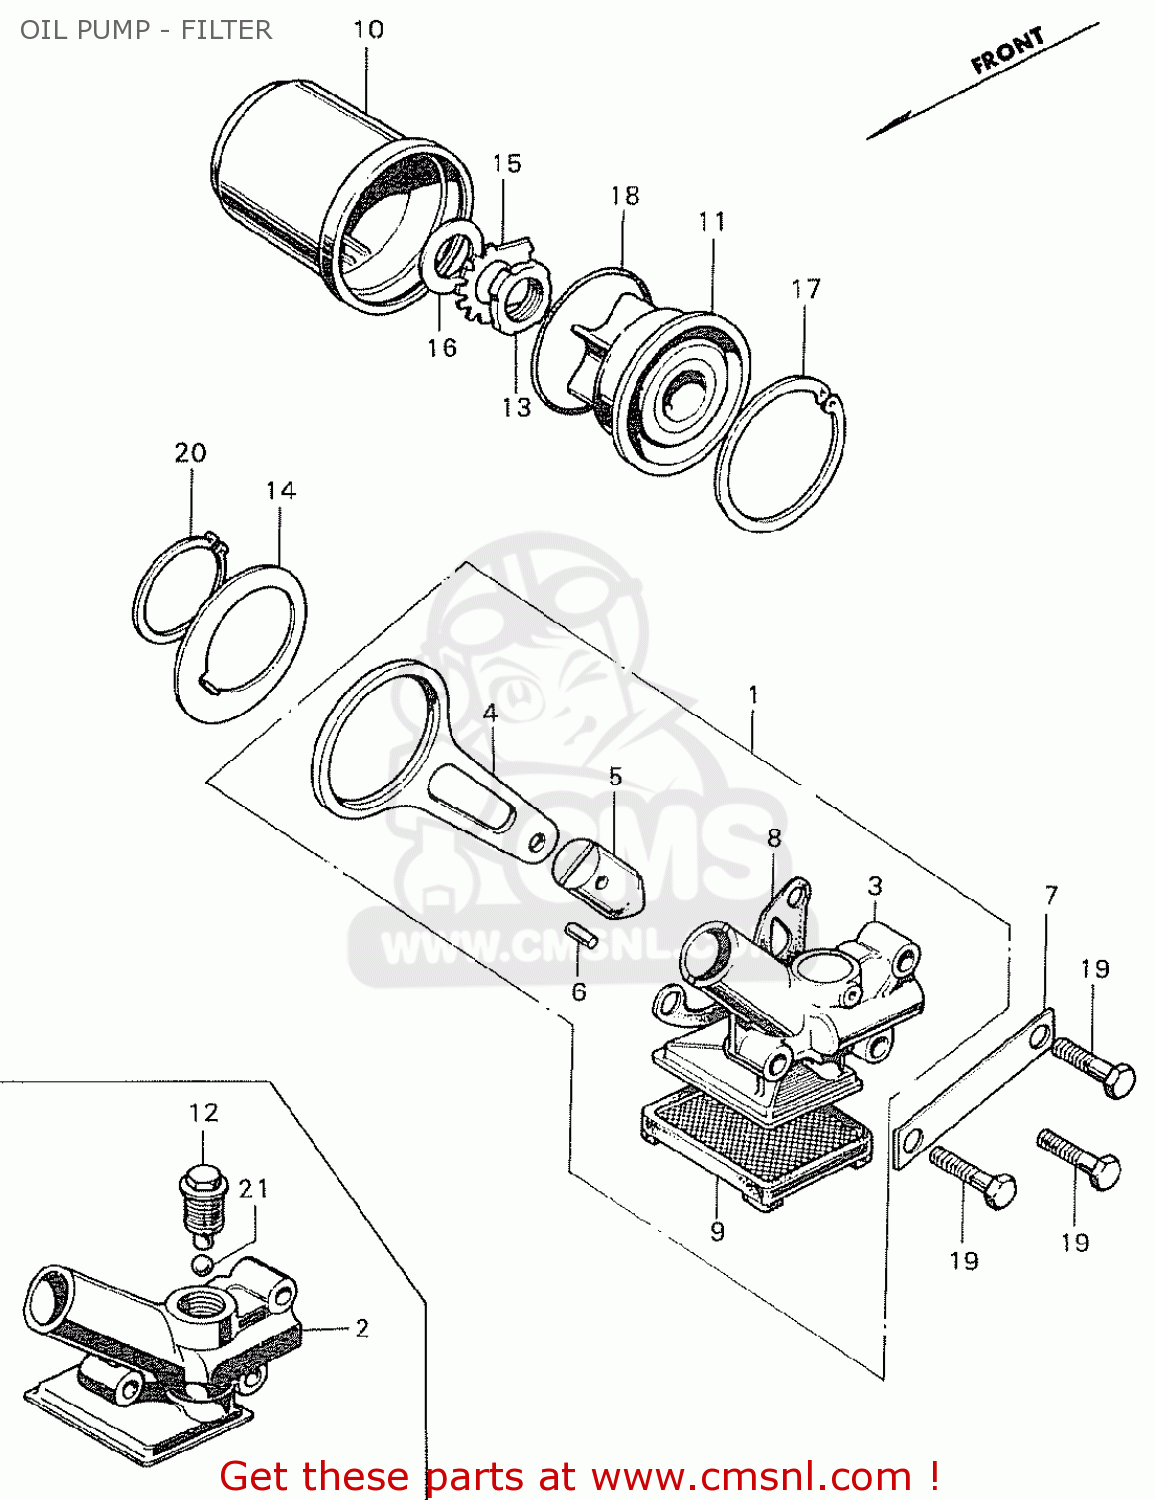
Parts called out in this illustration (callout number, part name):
1	PUMP ASSY,OIL
2	BODY, OIL PUMP
3	BODY,COMP.,PUMP
4	ROD,OIL PUMP
5	PLUNGER,OIL PUMP
6	PIN PUMP PLUNGER
7	WASHER,PUMP LOCK
8	GASKET,OIL PUMP (NAS)
9	SCREEN,OIL FILTER
10	ROTER,OIL FILTER
11	CAP,OIL FILTER
12	BOLT, SUCTION VALVE
13	NUT, LOCK, 16M/M
14	WASHER,RUMP ROD
15	WASHER,LOCK 16M/M
16	WASHER,16 MM FILTER LOCK
17	CLIP,CIR 45M/M
18	O RING,41X2
19	BOLT,HEX 6X32
20	CIR CLIP, 32MM
21	BALL,STEEL.,10
